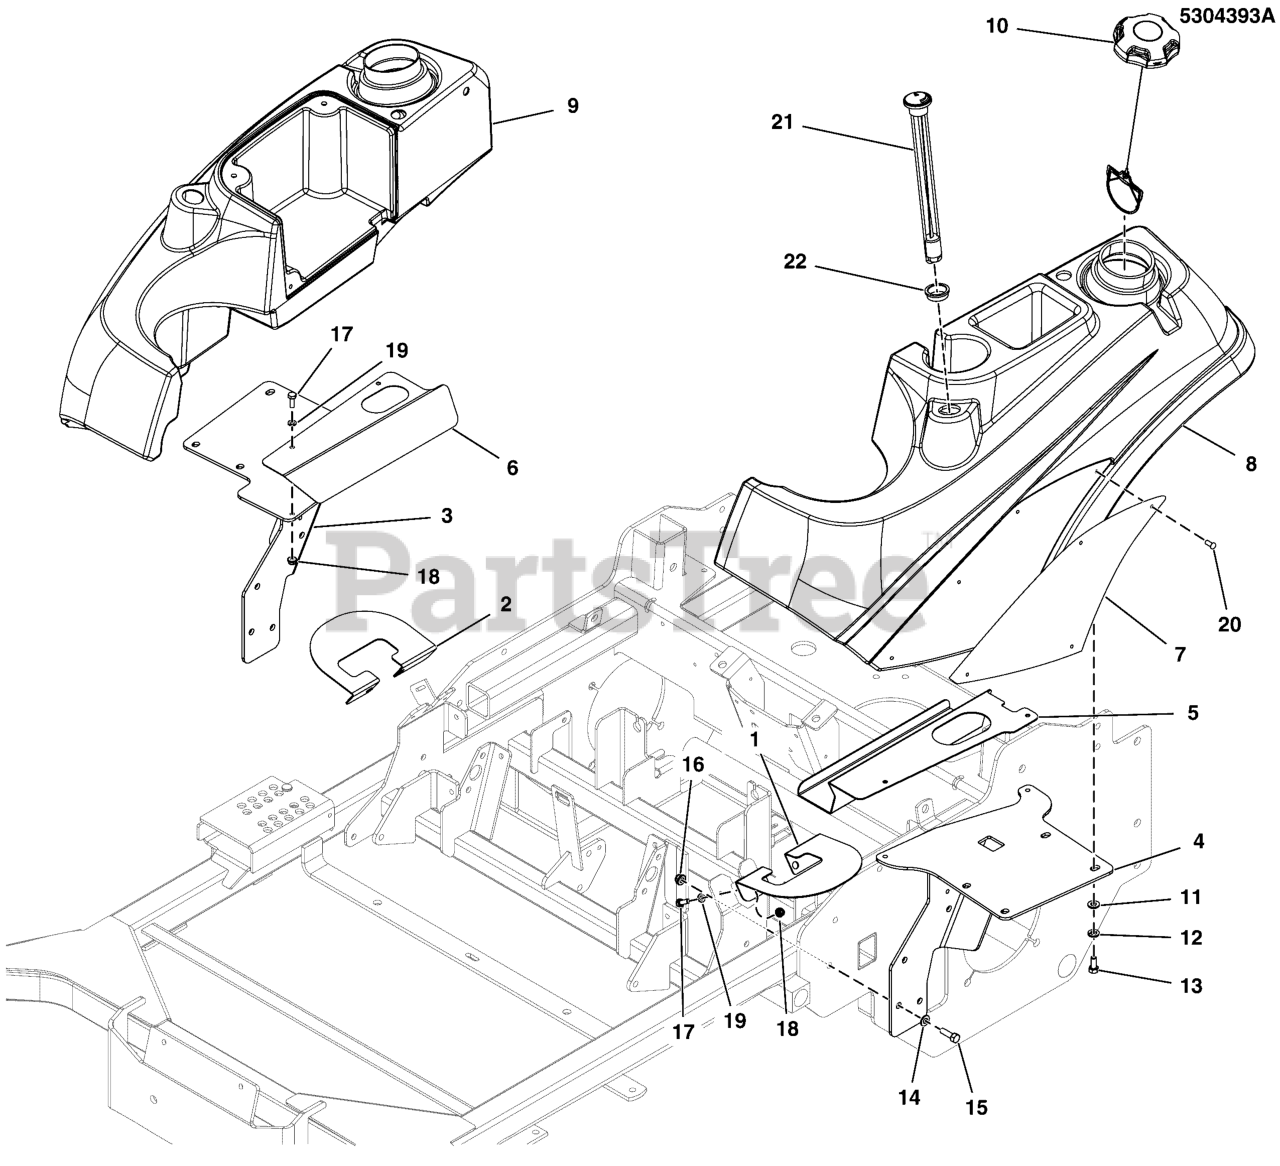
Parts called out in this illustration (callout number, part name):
1	PLATE, CONTROL GUARD,F320 LH,F210 RH-BLK
2	PLATE, CONTROL GUARD,F320 RH,F210 LH-BLK
3	WELD, FUEL MOUNT, RH - BLK
4	WELD, FUEL MOUNT, LH - BLK
5	GUARD, SEAT, LH, F210Z - BLK
5	GUARD, SEAT, LH - BLK
6	GUARD, SEAT, RH, F210Z - BLK
6	GUARD, SEAT, RH - BLK
7	BADGE, IS2000 - IS3000 - RED
8	TANK, FUEL, LH
9	TANK, FUEL, 5.25 GAL,MED, Z-RH, LOW PERM
10	FUEL CAP, 3-1/2", MANAGED VENT OUT, 12"
11	WASHER, 5/16 F436 FLAT
12	WASHER, 5/16 LOCK CZ
13	BOLT, 5/16-18 X 3/4 GD5
14	WASHER, 3/8 SAE
15	BOLT, 3/8-16 X 1" GD5 CZ
16	NUT, 3/8-16 HEX NYLOCK FLANGE
17	BOLT, 1/4-20 X 3/4 GD5 CZ
18	NUT, 1/4-20 HEX NYLOCK FLANGE
19	WASHER, 1/4 SAE
20	SCREW, #10-24 X 3/8 ALLEN BHBZ
21	GAUGE, FUEL, 12
22	GROMMET, FUEL GAUGE
